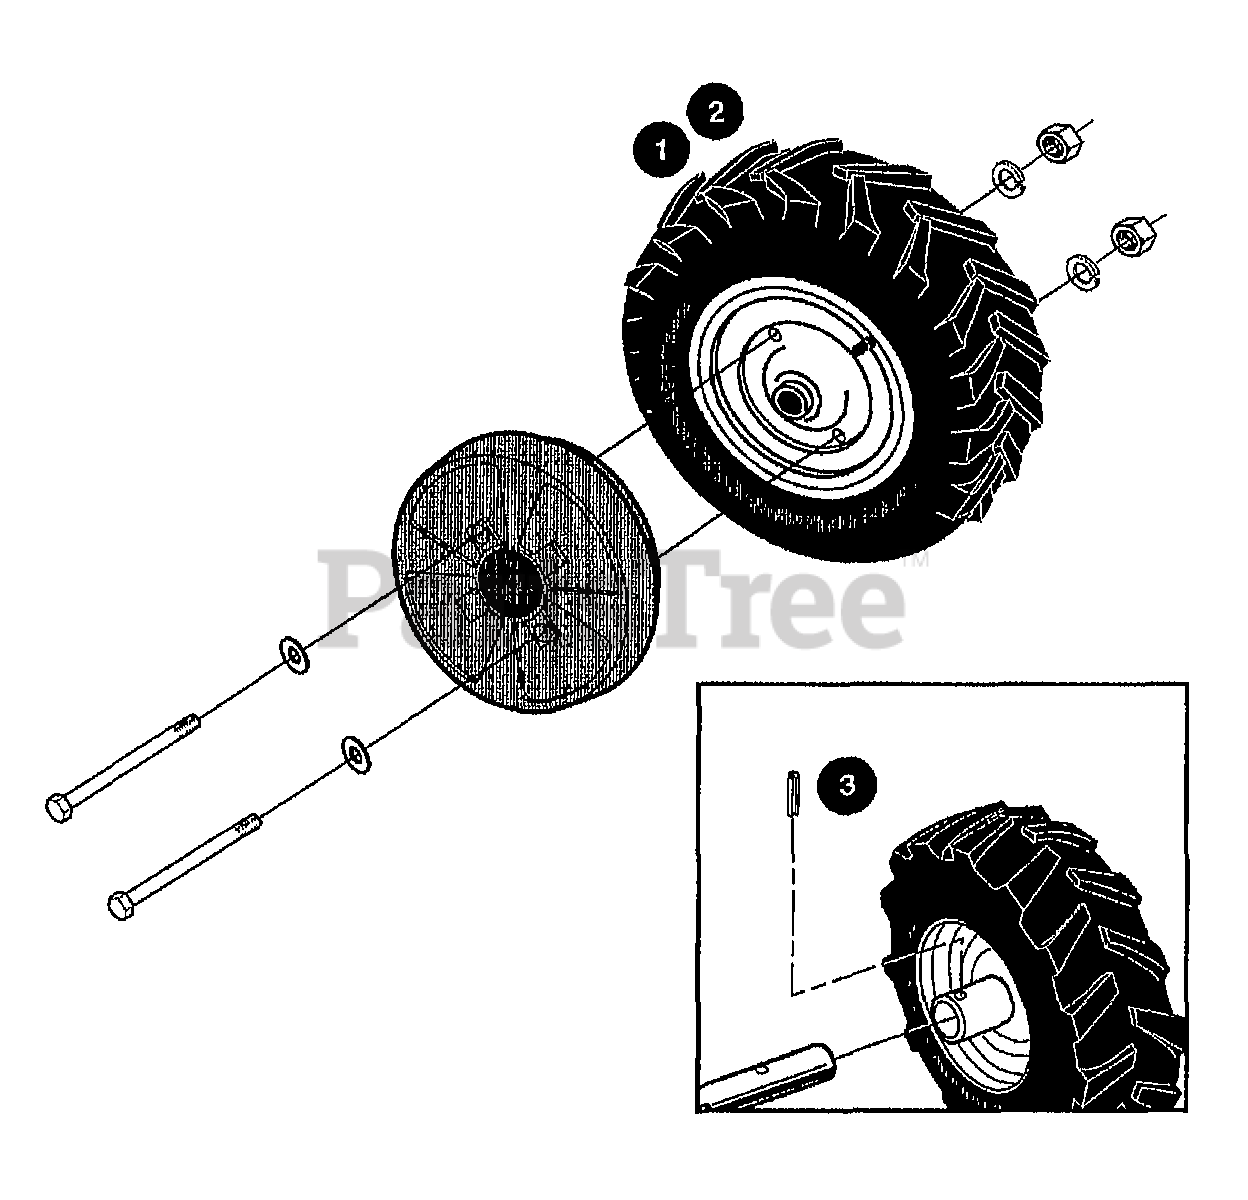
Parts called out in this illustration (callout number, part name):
1	ASSM-TIRE/WHL LT W/HOLE
2	ASSM-TIRE/WHL RT W/HOLE
3	PIN-SPRING .312X1.5
